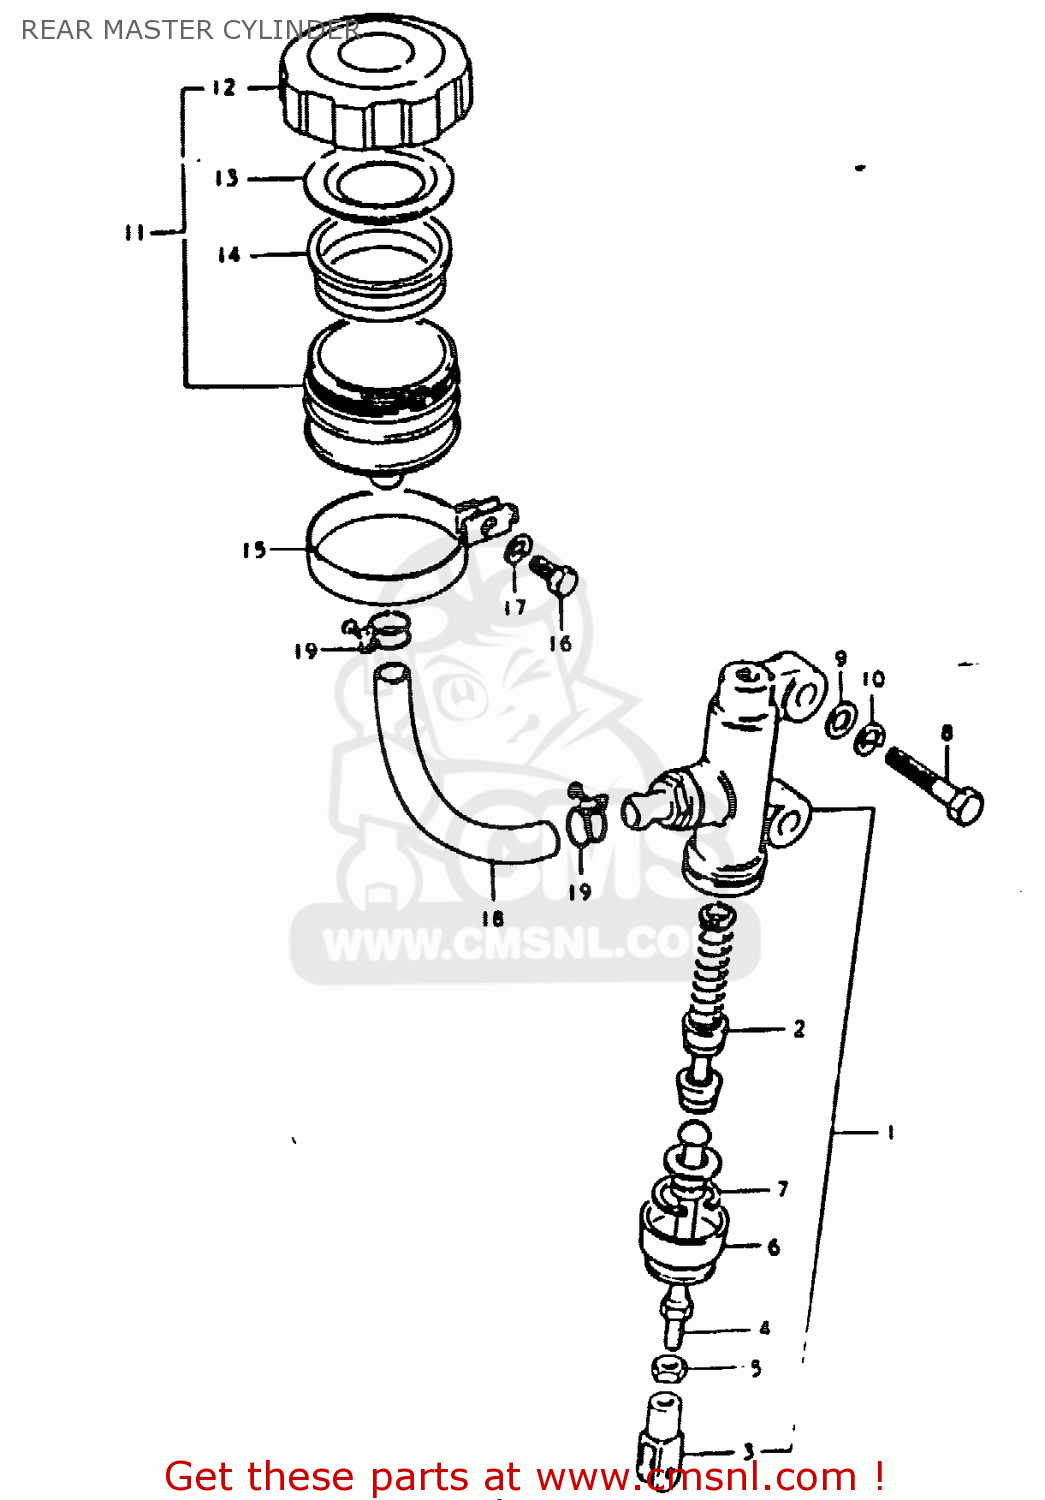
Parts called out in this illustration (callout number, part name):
1	CYLINDER ASSEMBLY,REAR MASTER
2	PISTON/CUP SET
3	YOKE
4	ROD,PUSH
5	NUT
6	BOOT
7	CIRCLIP
8	BOLT (8X30)
9	WASHER
10	LOCK WASHER
11	TANK ASSEMBLY,RESERVOIR
12	CAP
13	PLATE,DIAPHRAGM
14	DIAPHRAGM
15	CLAMP
16	BOLT, UPPER
17	LOCK WASHER
18	HOSE,RESERVOIR TANK
19	CLAMP
